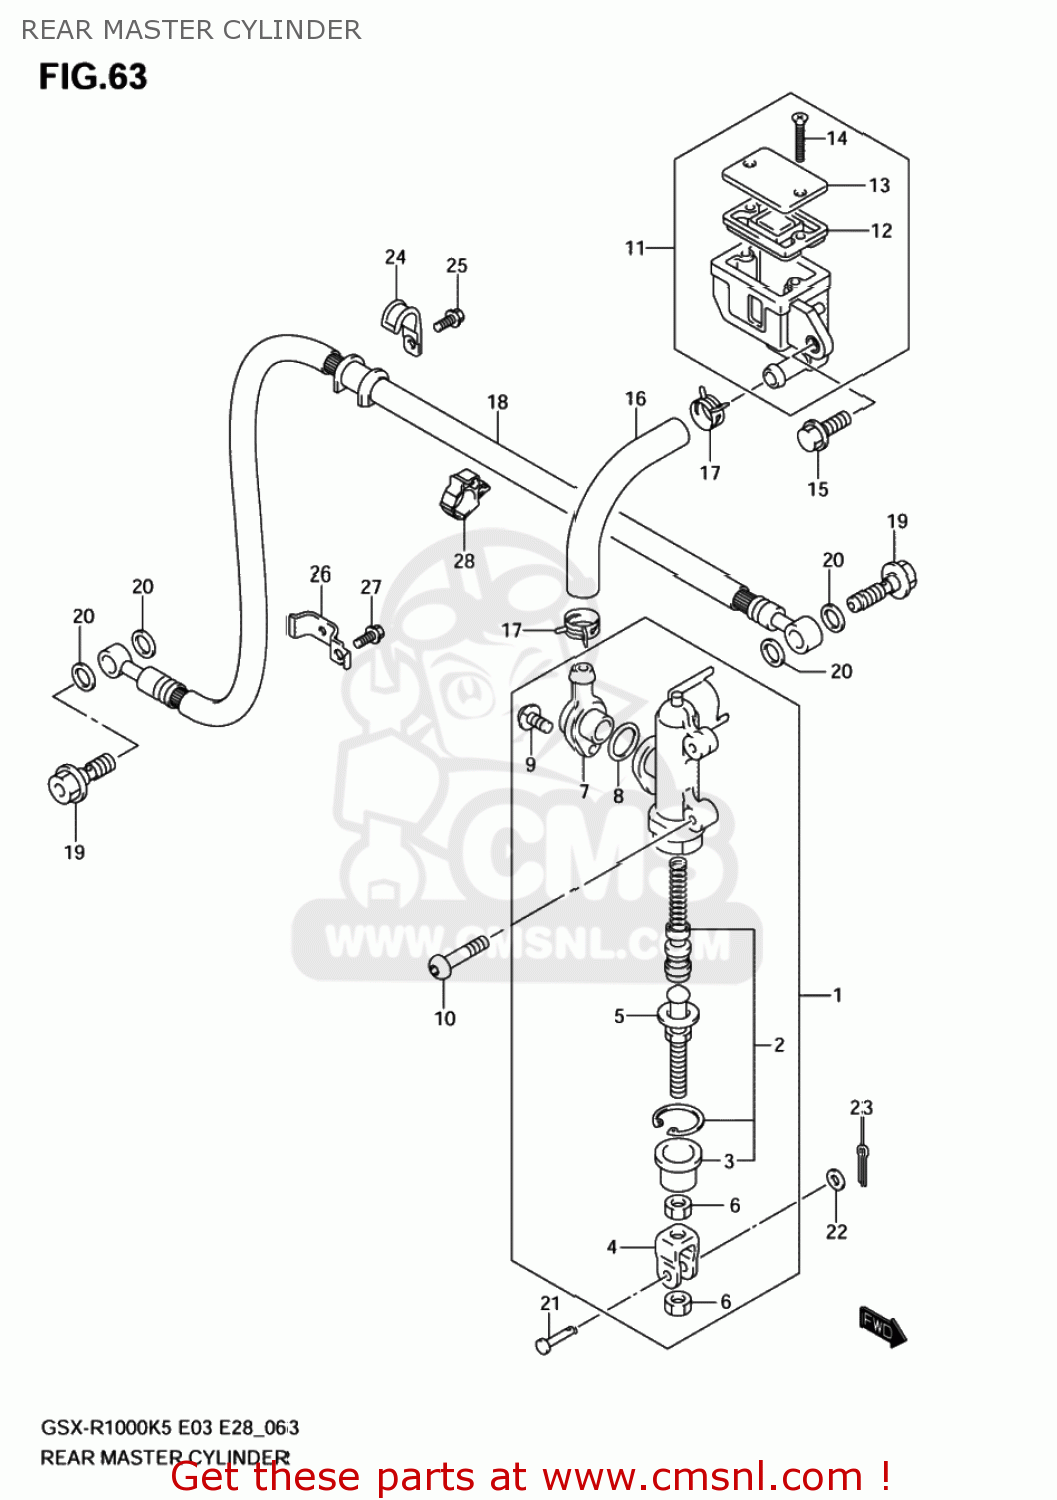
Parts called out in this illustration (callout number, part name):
1	CYLINDER ASSY,RR MASTER
2	PISTON/CUP SET
3	BOOT
4	YOKE
5	ROD,PUSH
6	NUT
7	CONNECTOR
8	O RING
9	SCREW
10	SCREW(6X20)
11	TANK ASSY,RESERVOIR
12	DIAPHRAGM
13	CAP
14	SCREW
15	BOLT(6X12)
16	HOSE,RR RESERVOIR TANK
17	CLIP
18	HOSE,REAR BRAK
19	BOLT UNION
20	WASHER(10X15X1.5)
21	PIN
22	WASHER
23	PIN
24	CLAMP,RR BRAKE HOSE
25	BOLT
26	GUIDE,RR BRAKE HOSE
27	BOLT
28	CLAMP
